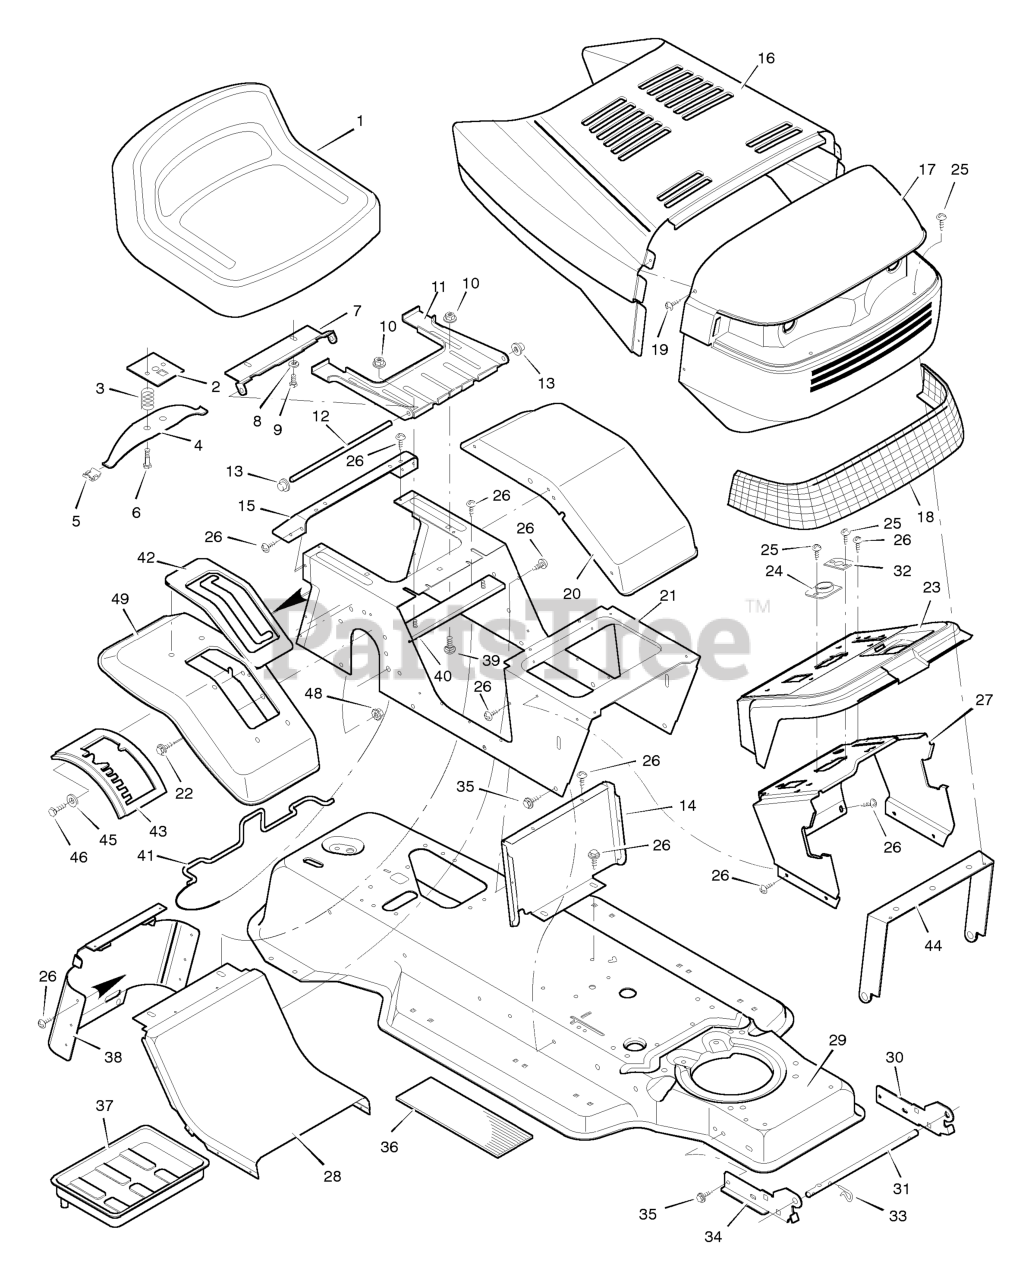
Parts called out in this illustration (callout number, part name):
2	Plate Assembly, Switch
3	Spring, Compression
4	Spring, Seat
5	Glide, Spring
6	Bolt, Shoulder
7	Support, Seat
8	Lockwasher
9	Bolt, Hex
10	Locknut, Flange
11	Bracket, Pivot
12	Rod, Pivot
13	Cap, Push On
14	Insert, Front
15	Fender, Apron
17	Grille Assembly
21	Console Assembly
23	Dash Panel
24	Bearing, Steering
26	Screw
27	Support, Dash
28	Insert, Rear
29	Frame Assembly
30	Bracket, Left Grille
31	Rod, Pivot
32	Bearing
33	Pin, Hair
34	Bracket, Right Grille
37	Tray, Battery
38	Cap, Console
39	Bolt
40	Channel Assembly
41	Clamp, Battery
42	Cover, Shift
43	Gate, Shift
44	Brace, Grille
45	Washer
46	Bolt, Hex
48	Locknut
49	Fender, SOG
